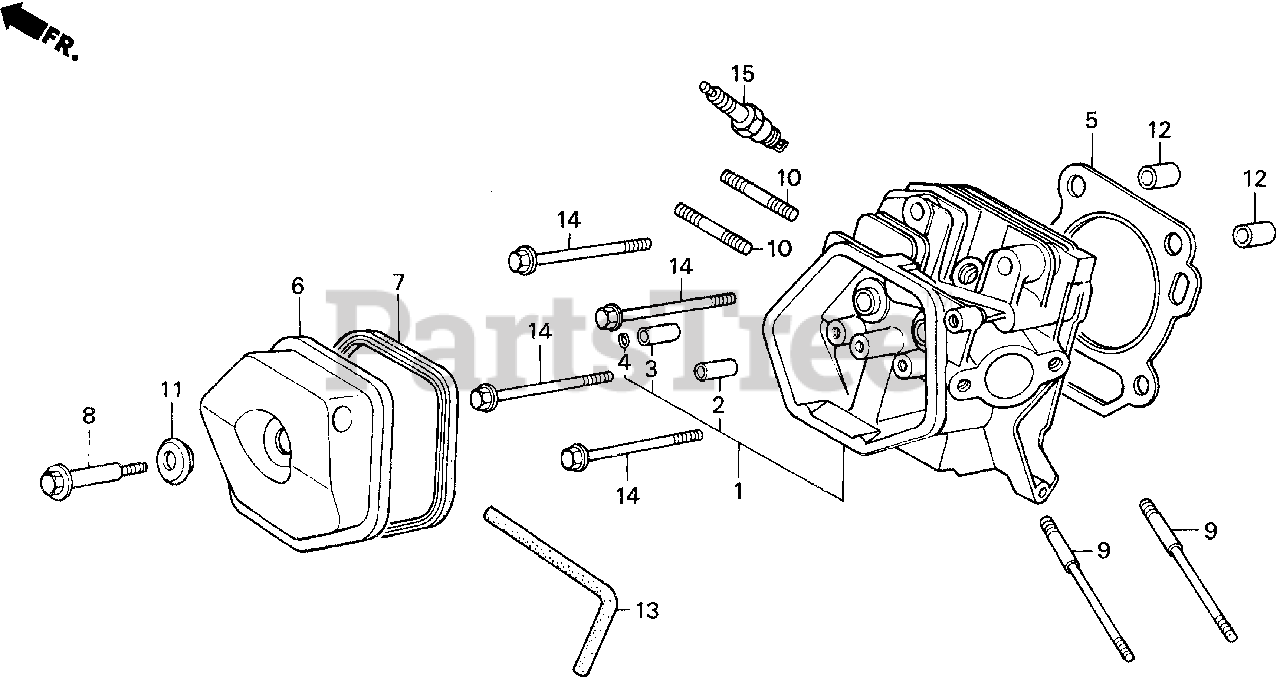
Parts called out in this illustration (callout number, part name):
1	CYLINDER HEAD
2	GUIDE, VALVE (OS)
3	GUIDE, EX. VALVE (OS)
4	CLIP, VALVE GUIDE
5	GASKET, CYLINDER HEAD
6	COVER, HEAD
7	GASKET, CYLINDER HEAD COVER
8	BOLT, HEAD COVER
9	BOLT, STUD (8X131.5)
10	BOLT, STUD
10	BOLT 2, STUD (8X32)
11	WASHER, HEAD COVER
12	PIN A, DOWEL (12X20)
13	BULK HOSE, VACUUM (11X1000) (11X105)
14	BOLT, FLANGE (10X80)
15	SPARK PLUG (BPR5ES) (NGK)
15	SPARK PLUG (W16EPR-U) (DENSO)
